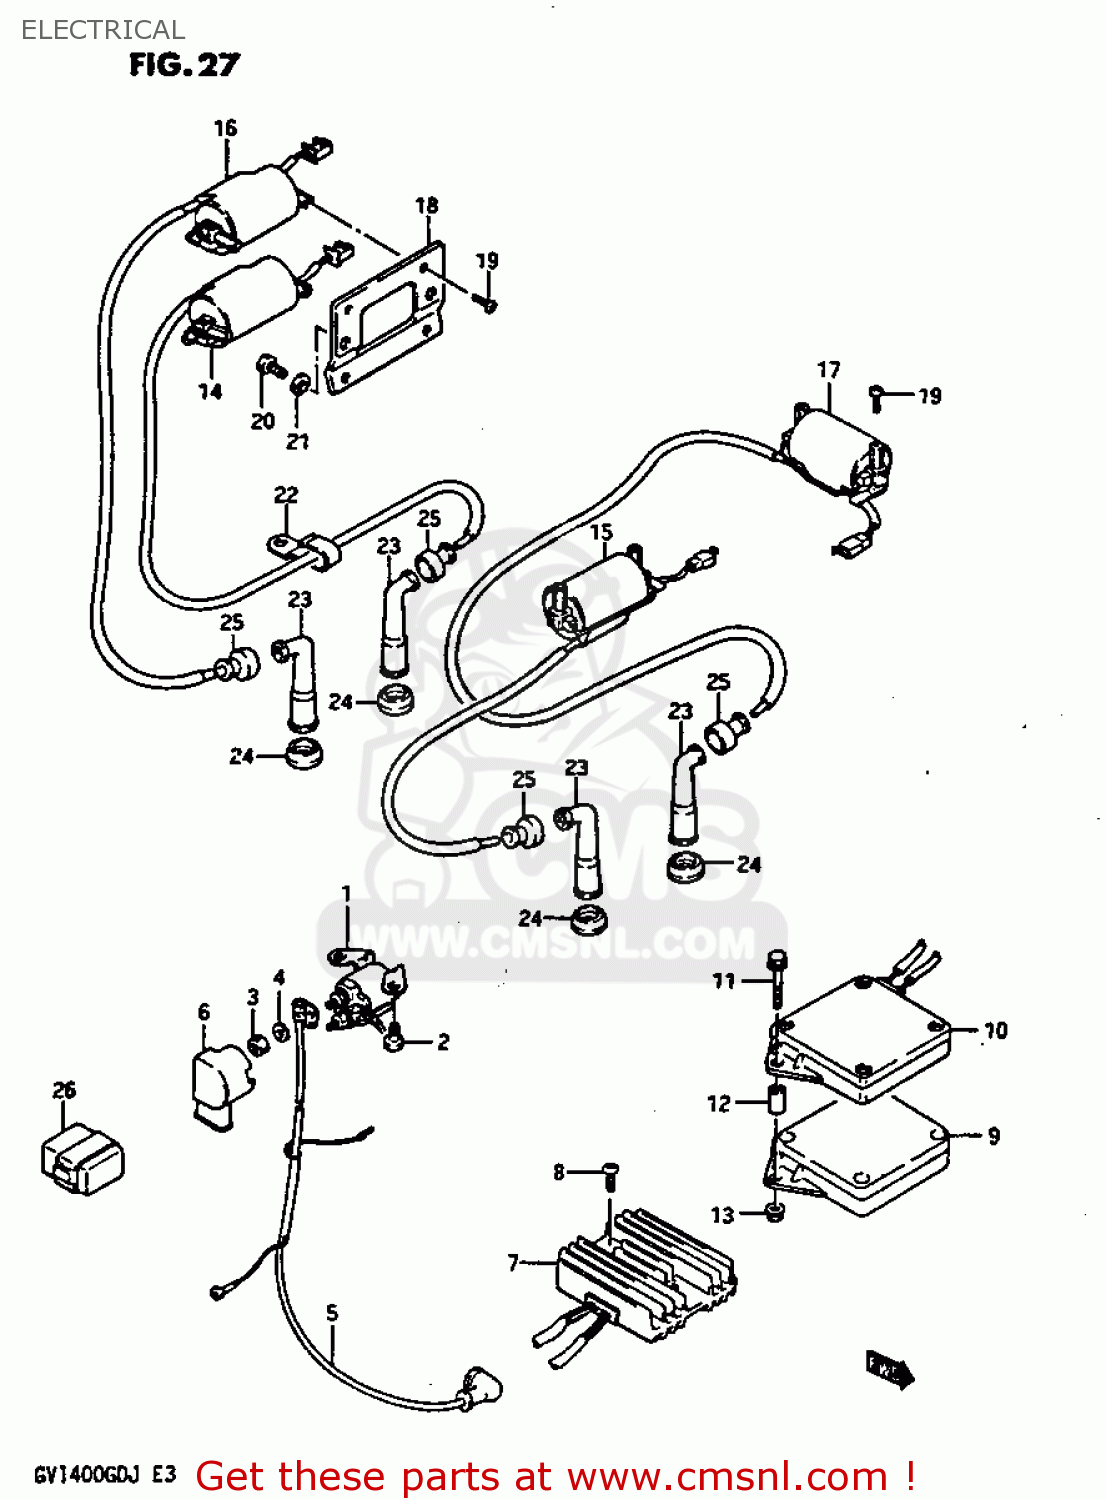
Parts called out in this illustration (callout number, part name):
1	RELAY ASSY,STARTING MOTOR
2	BOLT
3	NUT
4	WASHER,LOCK
5	WIRE,STARTER MOTOR LEAD
6	CAP,STARTER RELAY TERMINAL
7	RECTIFIER ASSY
8	SCREW
9	IGNITER UNIT
10	IGNITER UNIT
11	BOLT
12	SPACER (6.4X9X21.5)
13	NUT
14	COIL ASSEMBLY,IGNITION
15	COIL ASSEMBLY,IGNITION
16	COIL, IGNITION NO.3
17	COIL ASSEMBLY,IGNITION
18	BRACKET,IGNITION COIL
19	SCREW 5X12
20	BOLT 8X12
21	WASHER 8MM
22	CLAMP
23	CAP ASSY,SPARK PLUG
24	SEAL,SPARK PLUG
25	SEAL,SPARK PLU
26	RELAY ASSY,FUEL CUT
